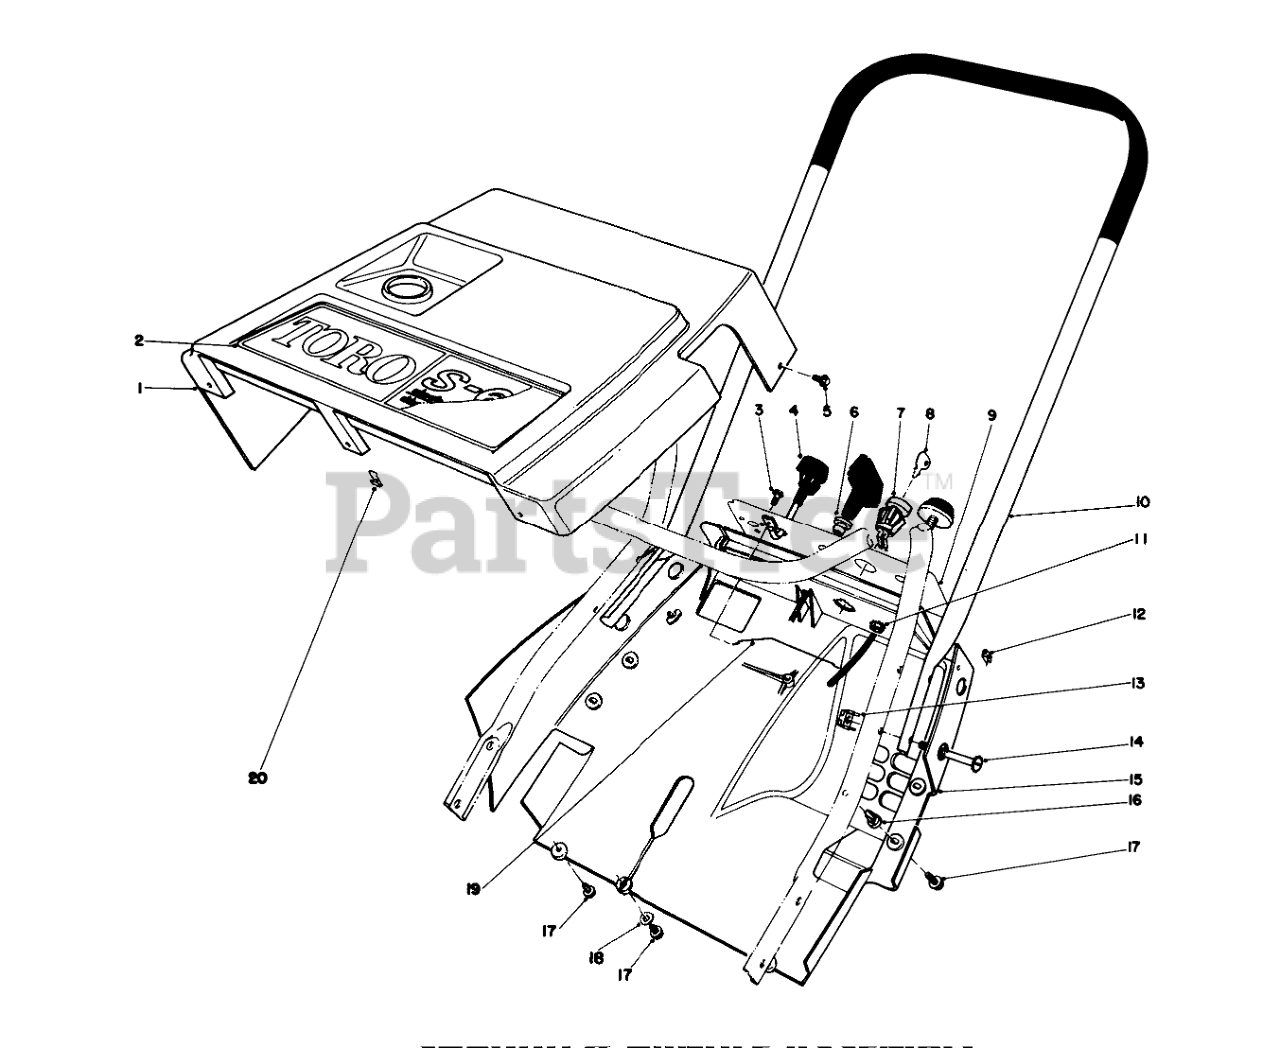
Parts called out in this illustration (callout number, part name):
1	Shroud-Upper
2	TORO DECAL
3	SCREW-PLASTITE
4	CHOKE CONTROL ASM
5	SCREW-HWHTF
6	GUIDE-ROPE, STARTER
7	SWITCH
8	Key
9	Decal-Control Panel
10	Handle-Upper
11	NUT-KEPS
13	TINNERMAN NUT
14	SCREW-HEX HD SLOT
15	LOWER SHROUD
16	Nut-Push
17	SCREW-HWHTF
18	WASHER-FLAT
19	CONTROL WIRE
20	NUT "U"
